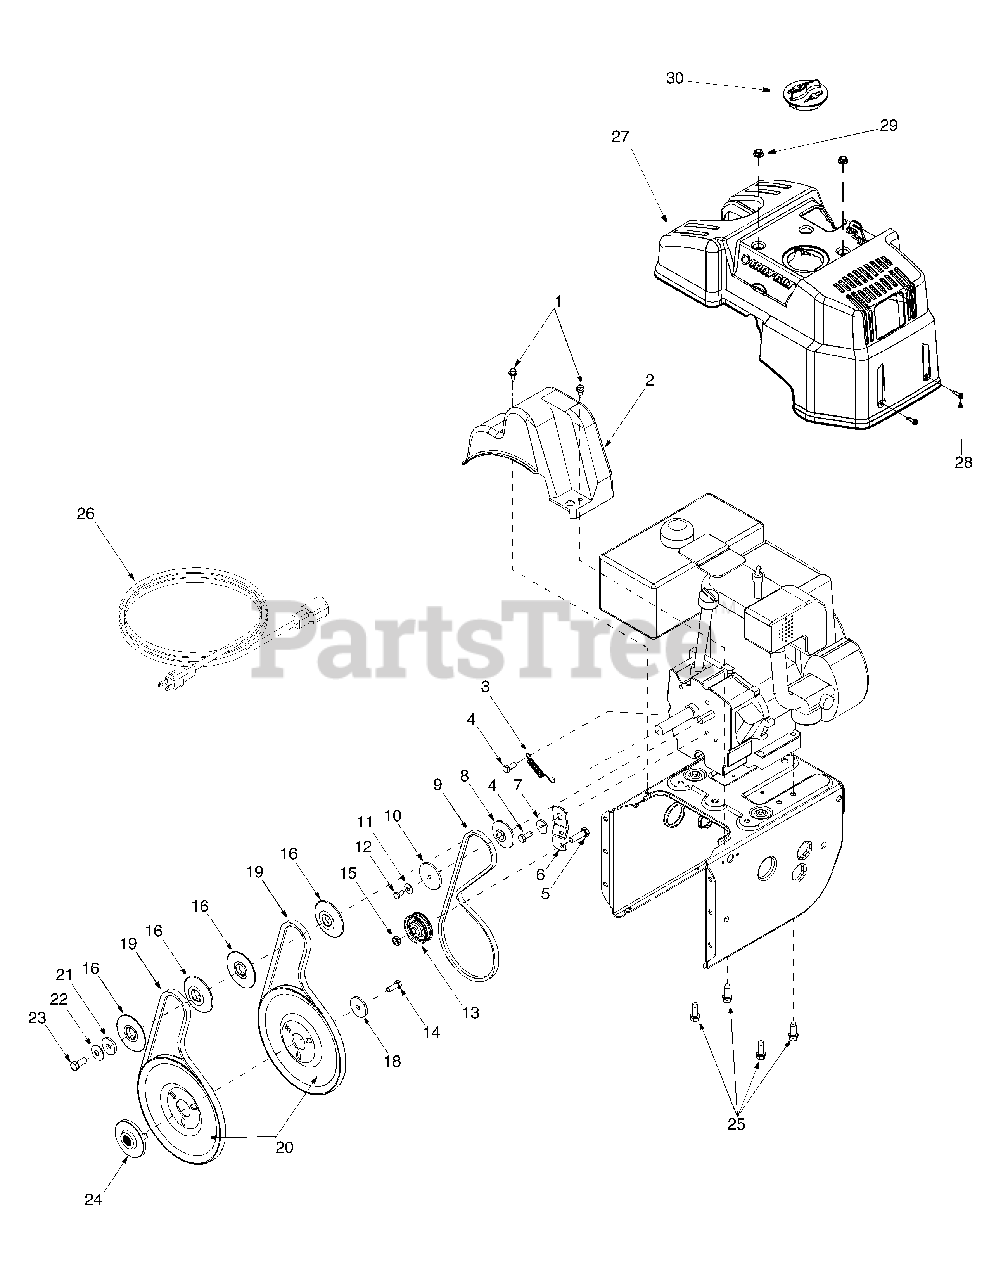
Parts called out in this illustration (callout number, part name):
1	Hex Washer Screw, 1/4-20 x.625
2	Belt Cover
3	Extension Spring
4	Hex Screw, 5/16-24 x.75
5	Hex Cap Screw, 3/8-16 x 1.25
8	Pulley Half
9	V-Belt
10	Pulley Half
11	Bell Washer
12	Hex Cap Screw, 1/4-28 x.50
13	Flat Idler
14	Lock Hex Cap Screw, 5/16-24
15	Lock Jam Nut, 3/8-16
16	Pulley Half
18	Flat Washer
19	Belt
20	Auger Pulley
21	Flat Washer, 3/8 x 1.25 OD
22	Bell Washer
23	Hex Cap Screw, 3/8-24
24	Adapter Pulley
25	Hex Screw, 3/8-16 x 1.0
26	Extension Cord
27	Engine Shroud
28	Screw, #10-16 x.75
29	Flange Lock Nut, 5/16-18
30	Spark Plug Cap
